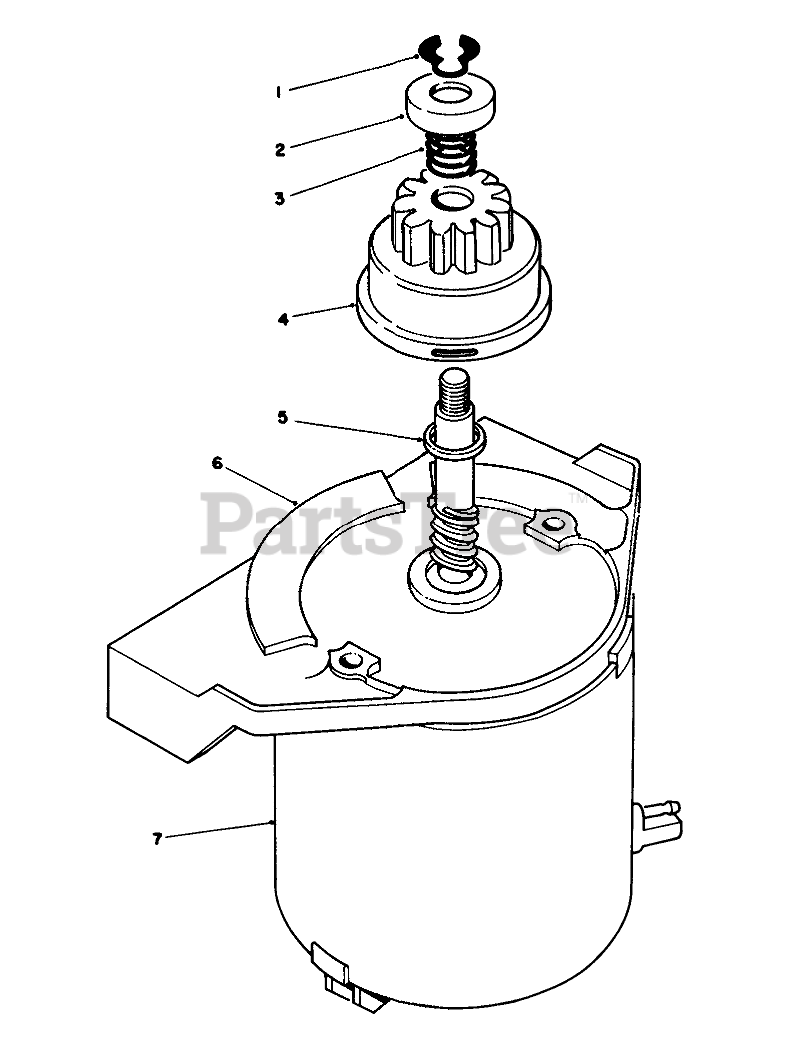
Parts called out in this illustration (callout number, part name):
1	RING-RETAINING
2	PINION STOP
3	COMPRESSION SPRING
4	Pinion Assembly
5	SPACER
6	END FRAME ASSY, MOTOR
7	Motor-Starter (Incl. Ref. #6)
